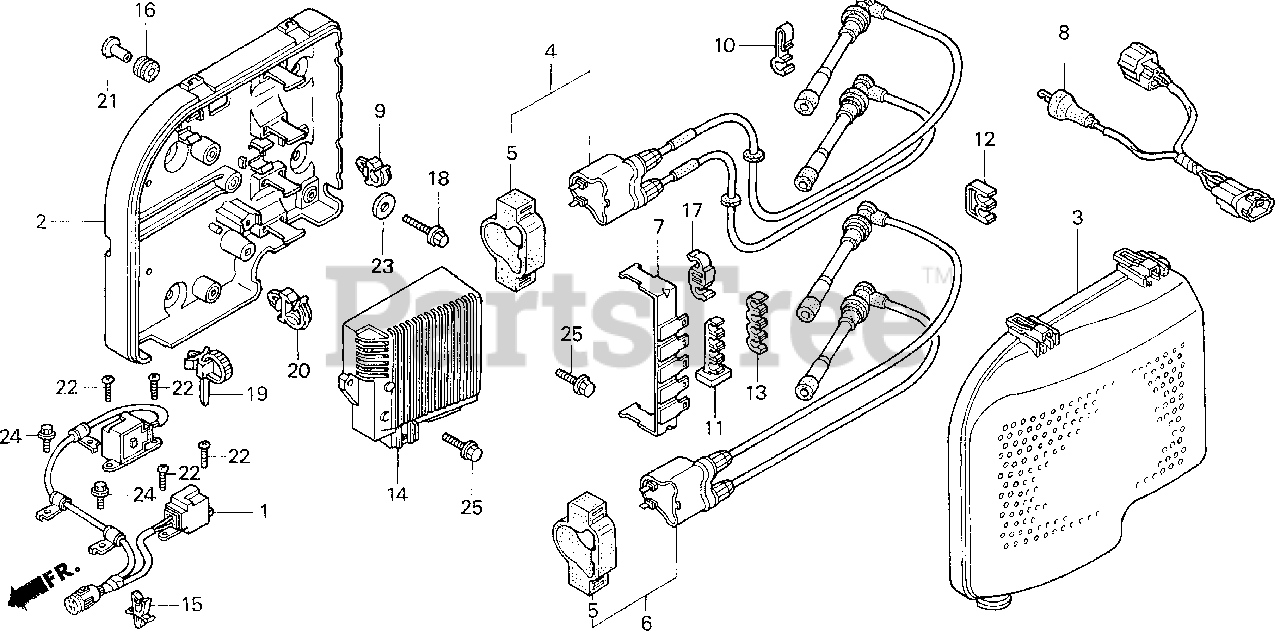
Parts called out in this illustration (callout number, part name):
1	COIL ASSY., PULSER
2	CASE, IGNITION CONTROL MODULE (CDI)
3	COVER, IGNITION CONTROL MODULE (CDI)
4	COIL ASSY., IGNITION (1,4)
5	SUSPENSION, IGNITION COIL
6	COIL ASSY., IGNITION (2,3)
7	BRACKET, CONNECTOR (A)
8	WIRE, SWITCH
9	CLAMP, WIRE
10	CLAMP, WIRE
11	CLAMP A, IGNITION WIRE
12	CLAMP B, IGNITION WIRE
13	GROMMET, IGNITION WIRE
14	CONTROL MODULE, ENGINE
14	CONTROL UNIT, ELECTRONIC
15	CLIP B, AIR TEMPERATURE SWITCH WIRE
16	GROMMET, CASE (LOWER)
17	CLIP A, WATER VALVE SOLENOID
18	BOLT, FLANGE (6X25)
19	STRAP, CABLE (118MM) (BLACK)
20	CLIP, WIRE HARNESS
21	COLLAR, MODULE IGNITION CONTROL CASE (CDI)
22	SCREW, PAN (5X14)
23	WASHER, PLAIN (6MM)
24	BOLT, FLANGE (6X12)
25	BOLT, FLANGE (6X16)
